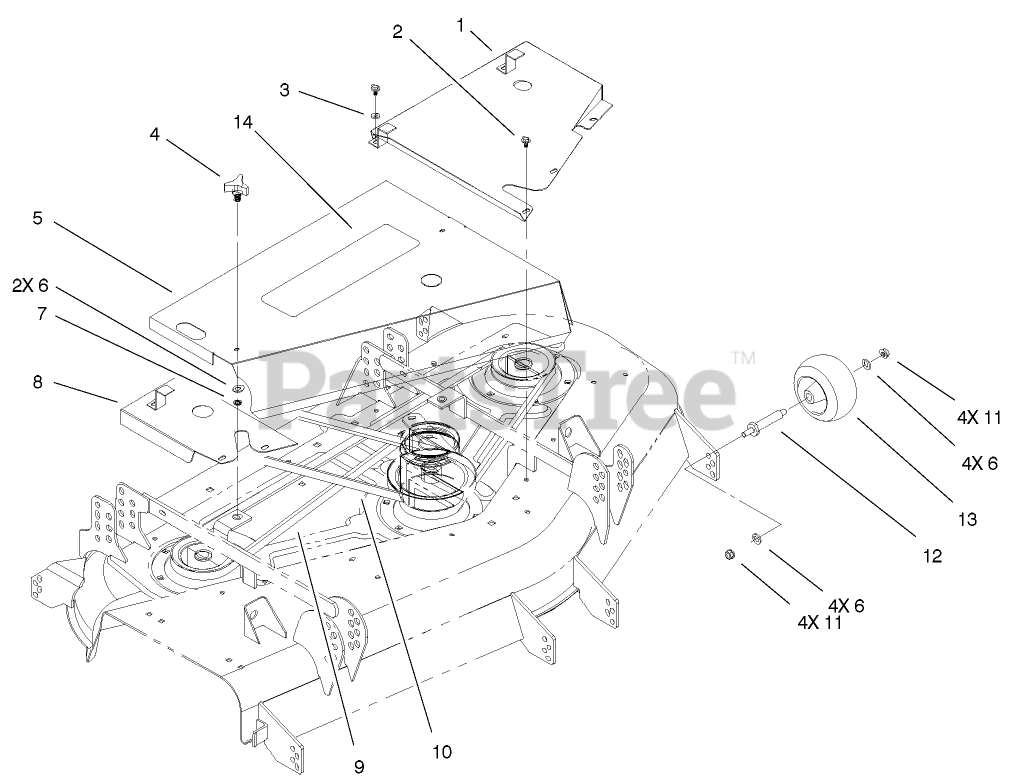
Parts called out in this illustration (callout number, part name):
1	LH COVER ASM
2	SCREW-HHFTF
3	WASHER-FLAT
5	COVER-CENTER
6	WASHER-FLAT
7	RING-RETAINING
8	RH COVER ASM
9	V-BELT
10	V-BELT-DECK DRIVE
11	NUT-LOCK, NI
12	SPACER
13	WHEEL-GAGE
14	DECAL
